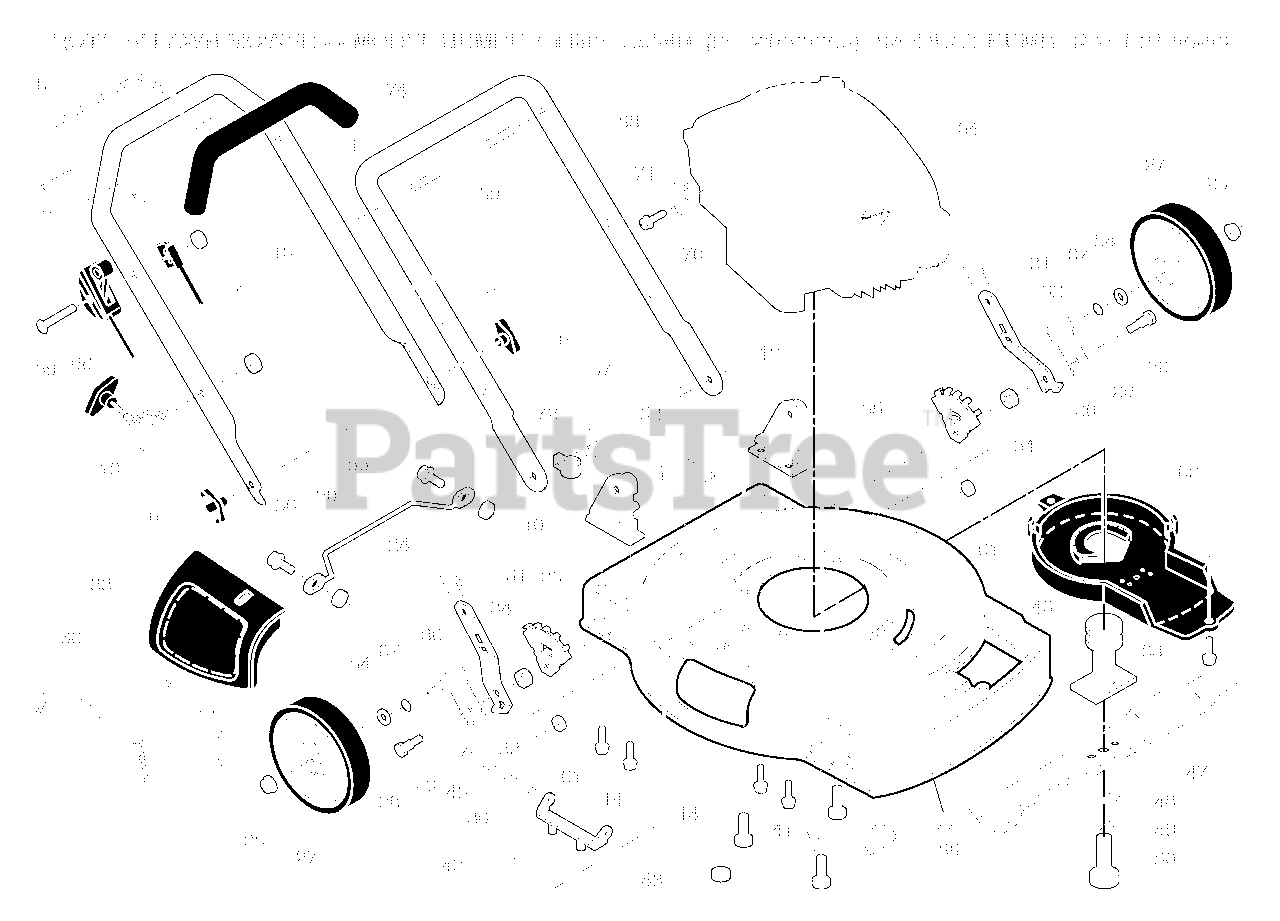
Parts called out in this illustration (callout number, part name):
2	ENGINE ZONE CONTROL CABLE
5	TIE GUIDE
6	KNOB, DEFLECTOR
10	HANDLE BRACKET ASM. RH
12	HANDLE BRACKET ASM. LH
14	SCREW 5/16-18
18	NUT
19	GUIDE.ROPE.STD.BLK.ZIN
25	NUT.HEX.FLANGE.3/8-16.LOCKNUT
28	BOLT
29	WASHER FLAT
30	AXLE ARM ASSY.
31	SELECTOR KNOB
32	SPRING.SEL.EXT.21.DOMED.12/14
34	SPACER.HEIGHT.ADJUSTER
35	BRACKET.ADJ.WHEEL.5POS.ADS
36	HINGE BRACKET
41	BOLT 3/8-16X1-1/8
42	TORSION SPRING
43	LOCKNUT
45	ROD.HINGE.COMBI-C
46	BLADE ADAPTOR / PULLEY
48	WASHER,HARDEN
49	LOCKWASHER
50	SCREW, HEX HD 3/8-24 X 1-3/8
52	DECAL.INTERNATIONL.CUTFINGER
54	WASHER PM
55	BRACKET
57	HAIRPIN COTTER
59	BOLT, HANDLE 5/16-18X1.75
61	LOCKNUT PM
62	DEBRIS SHIELD
63	SCREW.HEX.WSH
67	O-RING..070X.487.NEOPRENE
68	THROTTLE CONTROL
70	CABLE CLAMP(ENGINE)
71	SCREW.HEX.HEAD.WASHER.10-16
72	CLIP.CABLE.BLK
74	GRIP.HANDLE.FOAM
